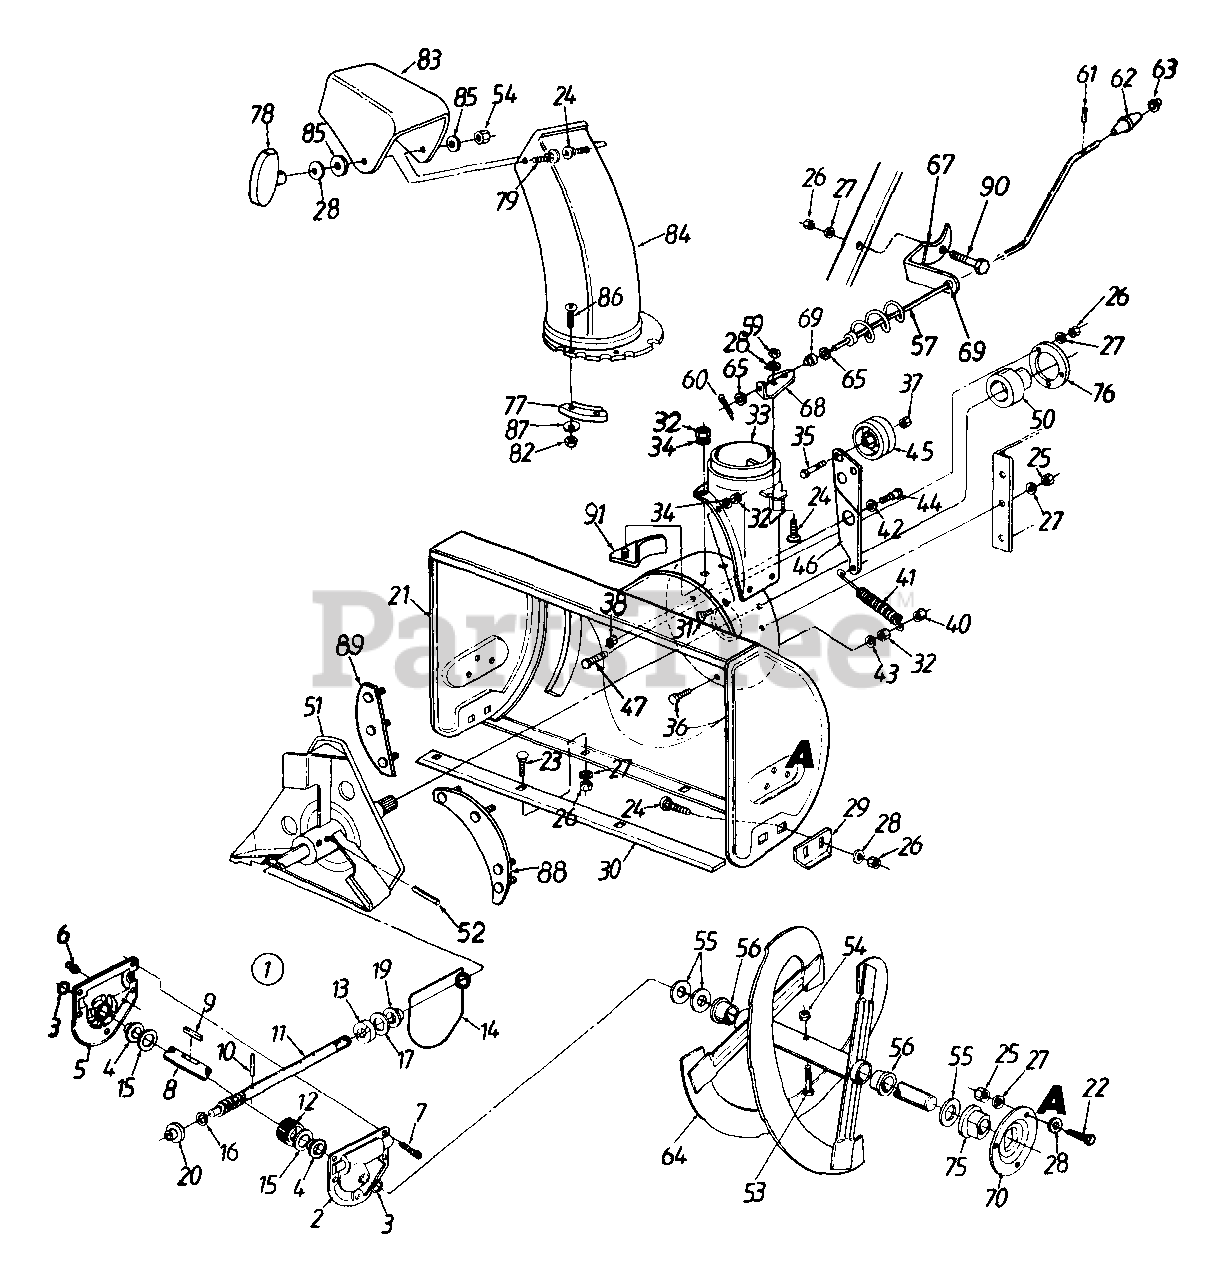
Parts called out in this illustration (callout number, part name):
1	Worm Drive Ass'y. Comp.
2	Reducer Housing - L.H.
3	Oil Seal
4	Flange Bearing .75" I.D.
5	Reducer Housing - R.H.
6	Grease Fitting
7	Hex TT-Tap Scr. 1/4-20 x .75" Lg.
8	24" Auger Shaft
9	#61 Hi-Pro Key 3/16" x 5/8" Dia.
10	Spiral Pin 1.25" Lg.
11	Impeller Shaft
12	Worm Gear
13	Thrust Collar
14	"O"-Ring
15	Fl-Wash. .76" I.D. x 1.5" O.D.
16	Fl-Wash. .5" I.D. x 1" O.D.
17	Fl-Wash. .76" I.D. x 1.49" O.D.
19	Flange Bearing .75" I.D.
20	Flange Bearing .503" I.D.
21	24" Auger Housing Ass'y.
22	Hex Bolt 5/16-24 x .75" Lg.
23	Carriage Bolt 5/16-18 x .62" Lg.
24	Carriage Bolt 5/16-18 x .75" Lg.
25	Hex Nut 5/16-24 Thd.
26	Hex Nut 5/16-18 Thd.
27	L-Wash. 5/16" I.D.
28	Bell-Wash. .345" I.D. x .88" O.D.
30	24" Shave Plate
31	Truss Mach. Scr. 1/4-20 x .5" Lg.
32	Hex Nut 1/4-20 Thd.
33	Chute Adapter
34	Spring Washer 1/4" I.D.
35	Hex Bolt 3/8-24 x 1.5" Lg. (Gr. 5)
36	Hex Bolt 1/4-20 x .75" Lg. (Gr. 5)
37	Hex Ins. L-Nut 3/8-24 Thd.
38	Hex Top L-Nut 3/8-16 Thd.
40	Hex L-Nut 1/4-20 Thd.
41	Ext. Spring 3.6" Lg.
42	Fl-Wash. 5/8" I.D. x 1.25"
43	L-Wash. 1/4" I.D.
44	Shld. Bolt .625" Dia. x .170" Lg.
45	Fl-Idler 2.75" O.D.
47	Hex Bolt 5/16-18 x 5/8" Lg.
50	Ball Bearing .75" I.D.
51	Blower Fan Ass'y.
52	Spiral Pin 1.5" Lg.
53	Shear Bolt 5/16-18 x 1.5" Lg.
54	Hex Cent. L-Nut 5/16-18 Thd.
55	Fl-Wash..76" I.D. x 1.49"
56	Flange Bushing .8" I.D.
57	Chute Crank Ass'y.
59	Hex Ins. L-Nut 5/16-18 Thd.
60	Cotter Pin 3/32" Dia. x .75"
61	Roll Pin 1/8" Dia. x .63" Lg.
62	Chute Crank Knob
63	Push Nut
65	Fl-Wash. .385" I.D. x.62" O.D.
69	Plastic Bushing .38" I.D.
75	Plastic Bearing w/Flats
76	Bearing Housing
77	Chute Flange Keeper
78	Knob Handle Ass'y.
79	Carriage Bolt 5/16-18 x 1" Lg.
82	Hex L-Nut 1/4-20 Thd.
83	Upper Chute
84	Lower Chute
85	Fl-Wash. .344" I.D. x 1.125"
86	Truss Mach. Scr. 1/4-20 x .75" Lg.
87	Fl-Wash. 1/4" I.D.
91	Chute Reinforcement
